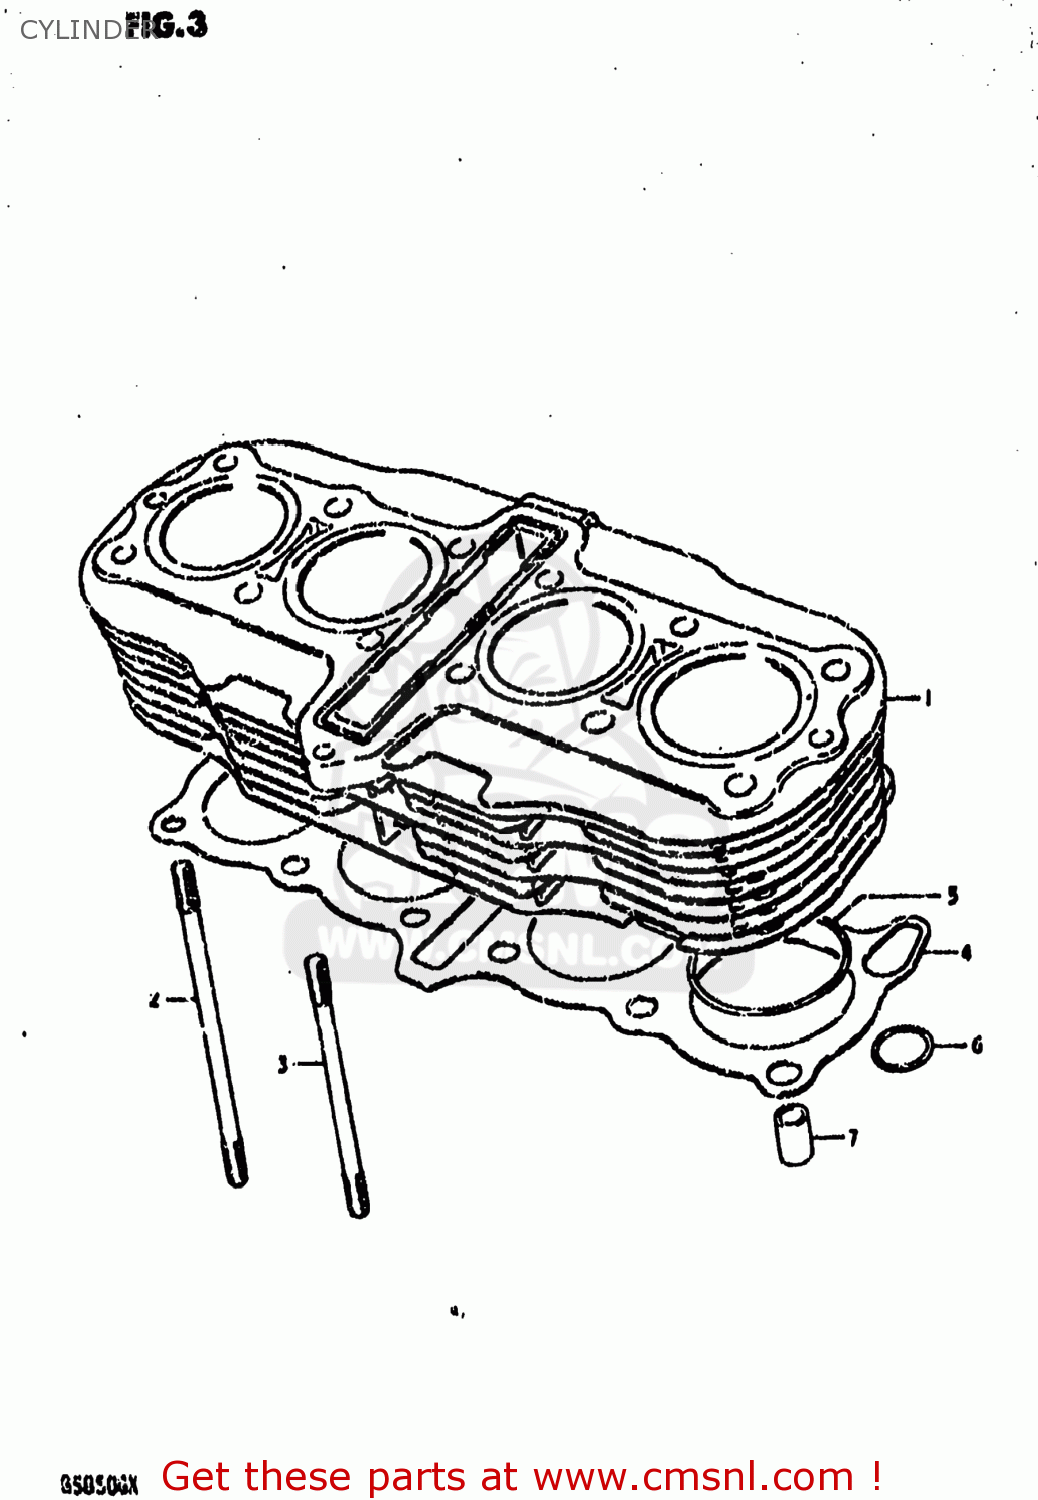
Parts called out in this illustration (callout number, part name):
1	CYLINDER
2	BOLT,STUD
3	BOLT
4	GASKET,CYLINDER (MCA)
5	O RING(D:2,ID:70)
6	O RING(D:3.05)
7	PIN
